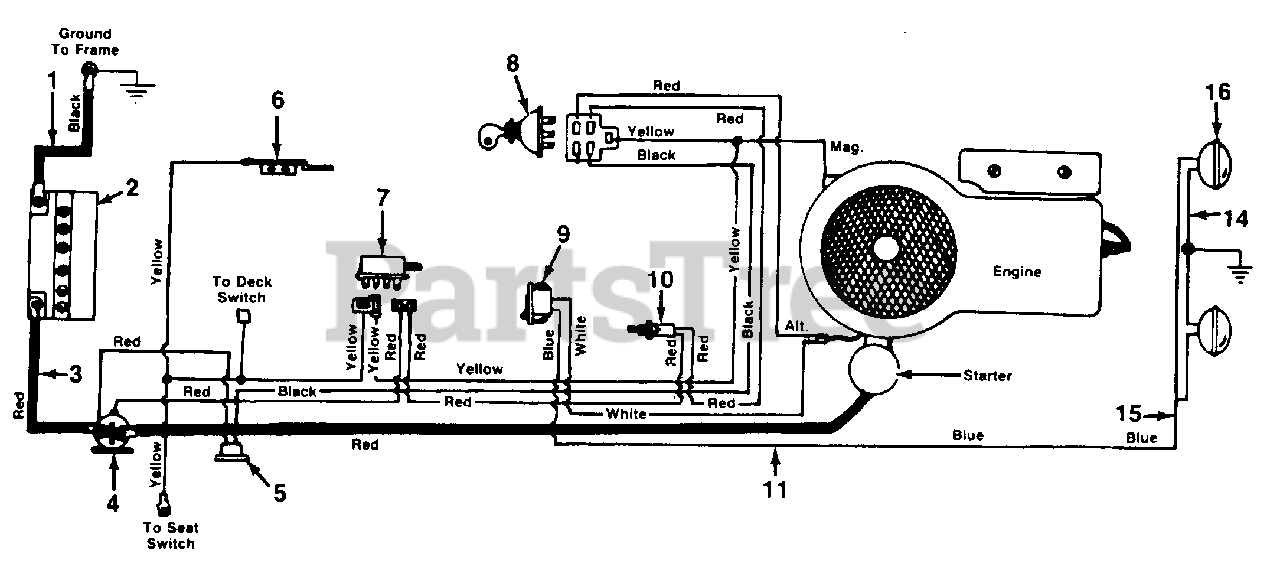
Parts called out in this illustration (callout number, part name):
1	Ground Wire
2	Battery
3	Electric Wire
4	Solenoid
5	Circuit Breaker
6	Spring Switch
7	Safety Switch
8	Key Switch
9	Light Switch
10	Safety Switch
11	Harness
14	Ground Wire
15	Headlight Harness
16	Lamp
